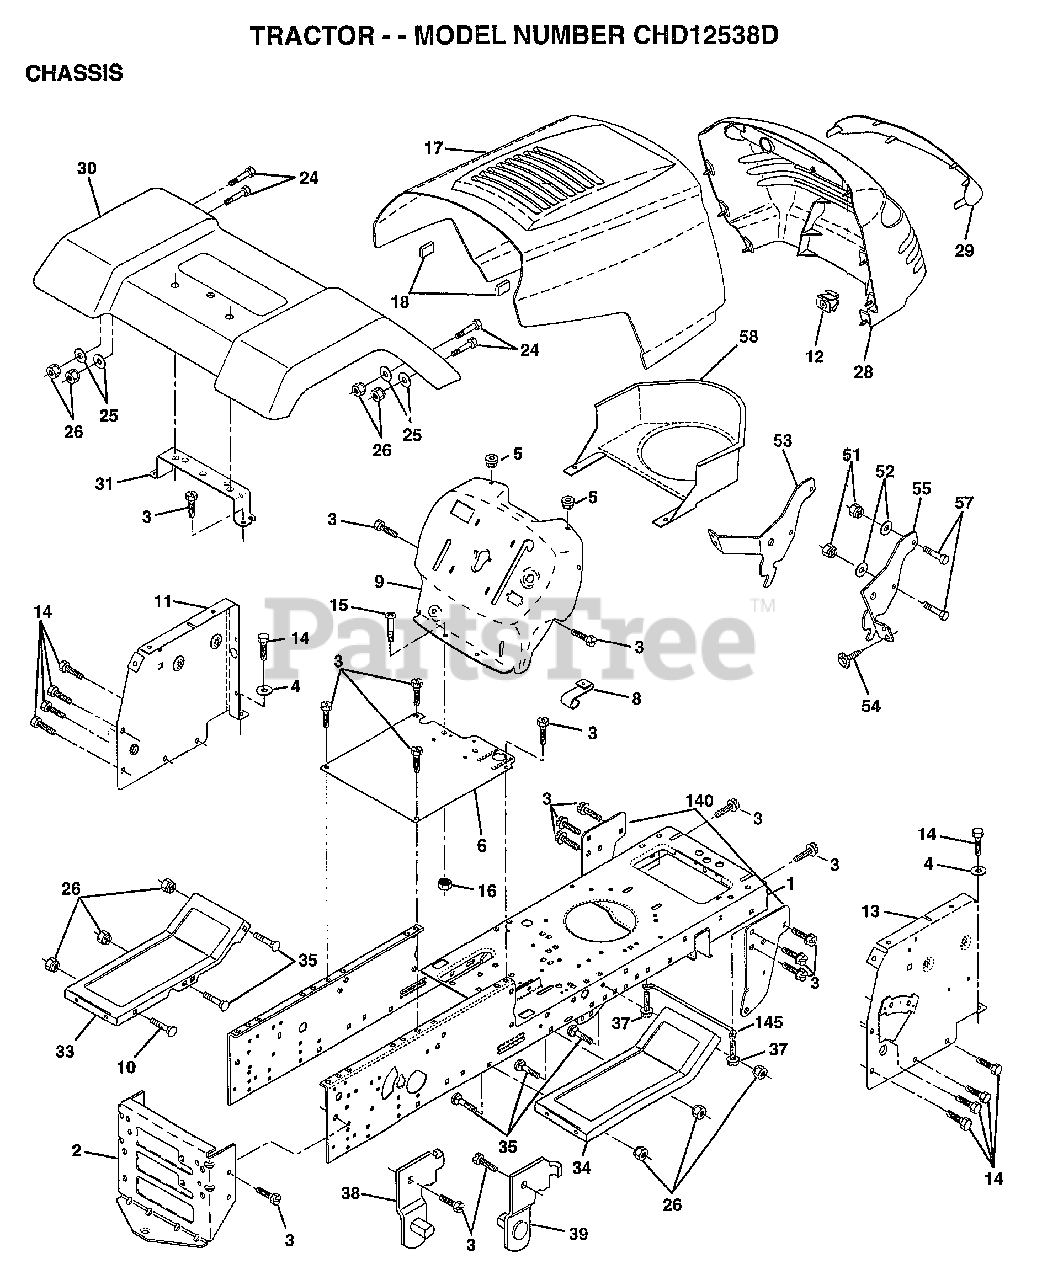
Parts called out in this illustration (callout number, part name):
1	CHASSIS.STAMPING
3	SCREW
4	WASHER
5	BUMPER-HOOD/DASH
6	"SADDLE FLAT,SLKSC"
8	CLIP.RETAINER
9	DASH SILKSCREEN
11	"PANEL-DASH,LH"
12	CLIP.TINNERMAN
13	PANEL.ASM.SLKSCR.DASH.RH
14	SCREW LT
15	SCREW
17	HOOD.STEEL.ASSY
24	BOLT
25	WASHER
26	NUT
28	GRILLE
29	LENS.GRILLE
30	FENDER.PNTL.LT.W/O.SHIFT
31	BRKT FENDER
33	FOOTREST.LH.PERF.
34	FOOTREST.RH.PERF.
35	BOLT
37	SCREW LT
38	BRACKET ASM LH
39	BRACKET ASM RH
51	NUT
52	WASHER
53	BRACKET.GRILLE.LH
54	SCREW.HEX.WS.HD
55	BRACKET.GRILLE.RH
58	AIR DUCT
140	BRKT SUSPENSION
145	"ROD POVOT,CHASSIS"
